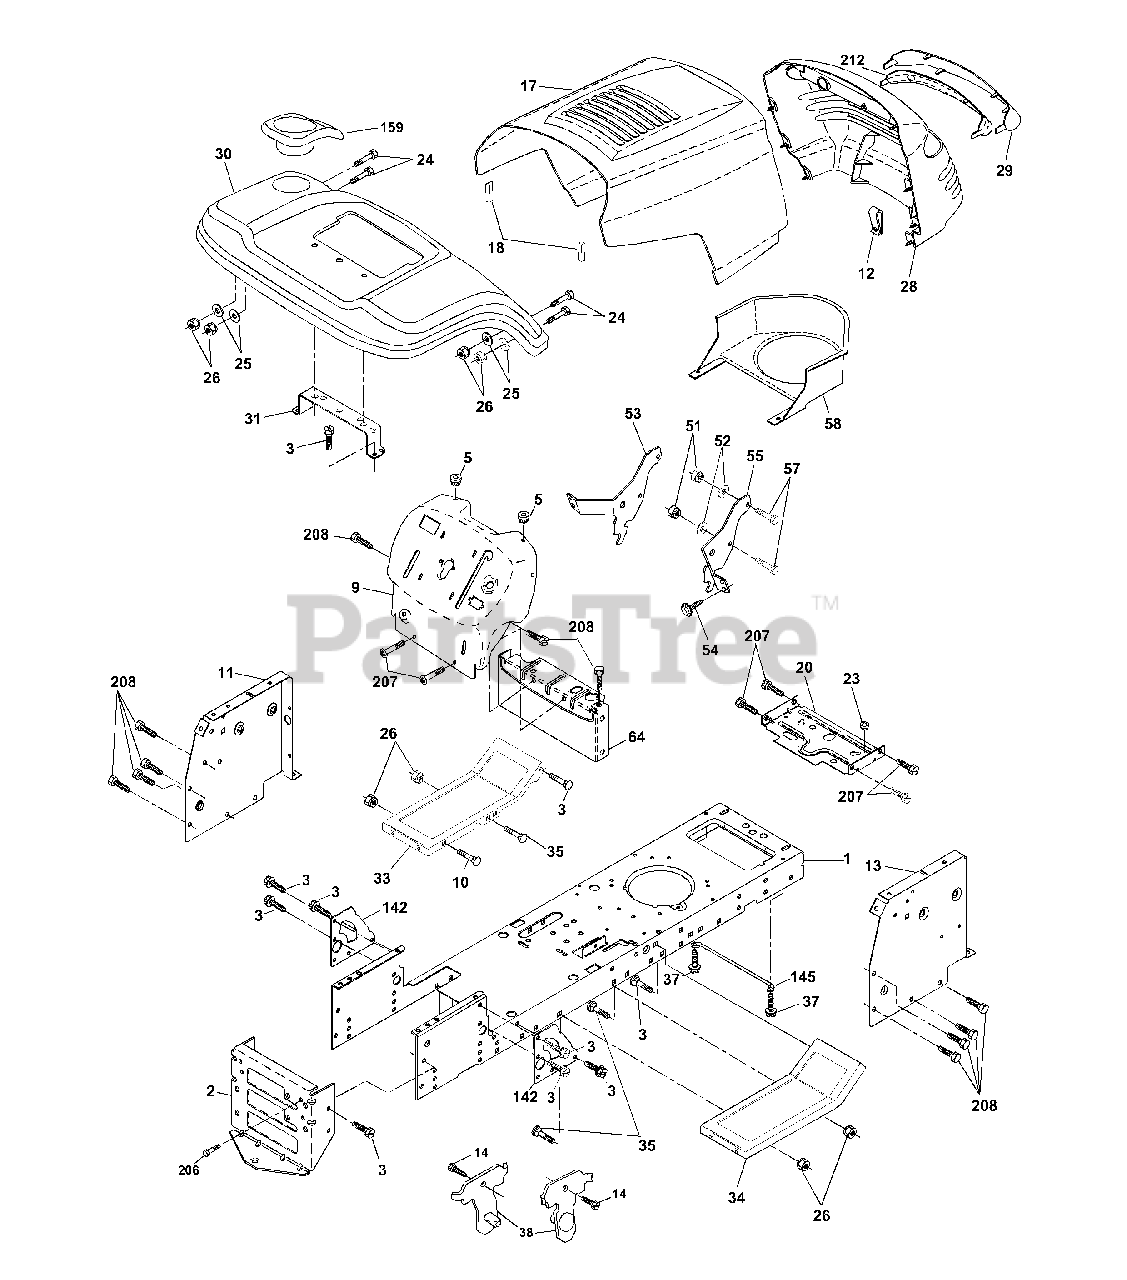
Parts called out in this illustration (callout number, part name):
1	Chassis
2	Drawbar
3	Screw 3/8-16x.75
5	Bumper Hood/Dash
9	Dash P/L
10	Bolt Carriage 3/8-16 x 1
11	Panel Dash Lh
12	Clip Tinnerman
13	Panel Dash Rh
14	Screw Thdrol 3/8-16 x 1-1/4
17	Hood LT/PL
18	Bumper Hood
20	Plate Mtg Battery Fuel Tank Fr
23	Bushing
24	Bolt Fin Hex 3/8-16 x 1 Gr 5
25	Washer 13/32 X 13/16 X 12 Ga
26	Nut Lock Hex W/Ins 3/8-16 Unc
28	Grille LT/PL
29	Lens LT/PL
30	Fender Footrest STLT Pnt
31	Bracket Support Fender
33	Footrest Pnt Lh
34	Footrest Pnt Rh
35	Bolt Rdhd Sht Sqnk 3/8-16 x 3/4
37	Screw Thdrol 6/16-18 x 1/2 TYT
38	Bracket Asm. Pivot Mower Rear
51	Nut Lock Hex W/Ins 1/4-20
52	Washer 9/32 x 7/8 x 16 Ga.
53	Bracjet Grukke Lh
54	Screw Hex Wshd 8-18 x 7/8
55	Bracket Grille Rh
57	Bolt Hex 1/4-20 x 3/4
58	Duct Air
64	Dash Lower STLT
114	Keeper Belt Rear Lh
115	Screw 3/8-16 x 1-1/4
142	Plate Reinforcement STLT
145	Rod Pivot Chassis/Hood
159	Cupholder
206	Bolt Shoulder 5/16-18
207	Screw Thdrol 5/16-18 x 1/2
208	Screw Thdrol 3/8-16 x 1/2
211	Nut Hex Flange Lock
212	Insert Lens Reflect P/L LT
